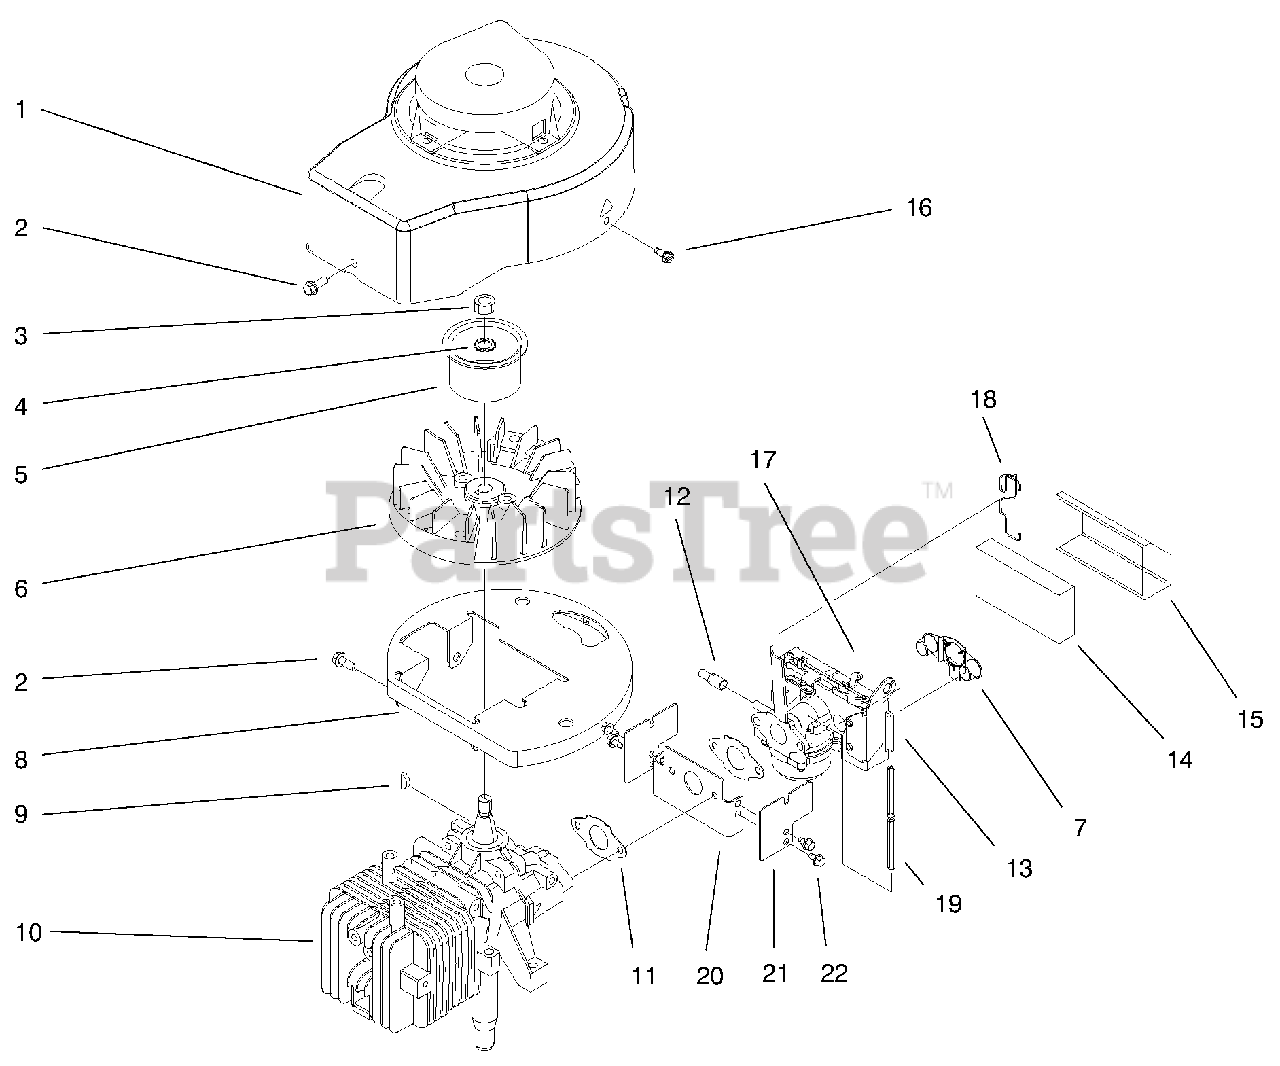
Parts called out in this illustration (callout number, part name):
1	ASM-Shroud & Recoil
2	Screw
4	Washer-Lock
5	Hub-Starter
6	ASM-Flywheel
7	Shield-Fuel
8	Base-Shroud
10	ASM-Short Block V
11	Gasket-Carburetor
13	ASM-Carburetor
14	Element-Filter
15	Cover-Air Filter
18	Retainer-Filter
19	Hose-Primer
20	Shield-Carb(Int'l)
21	Shield-Governor V(Int'l)
